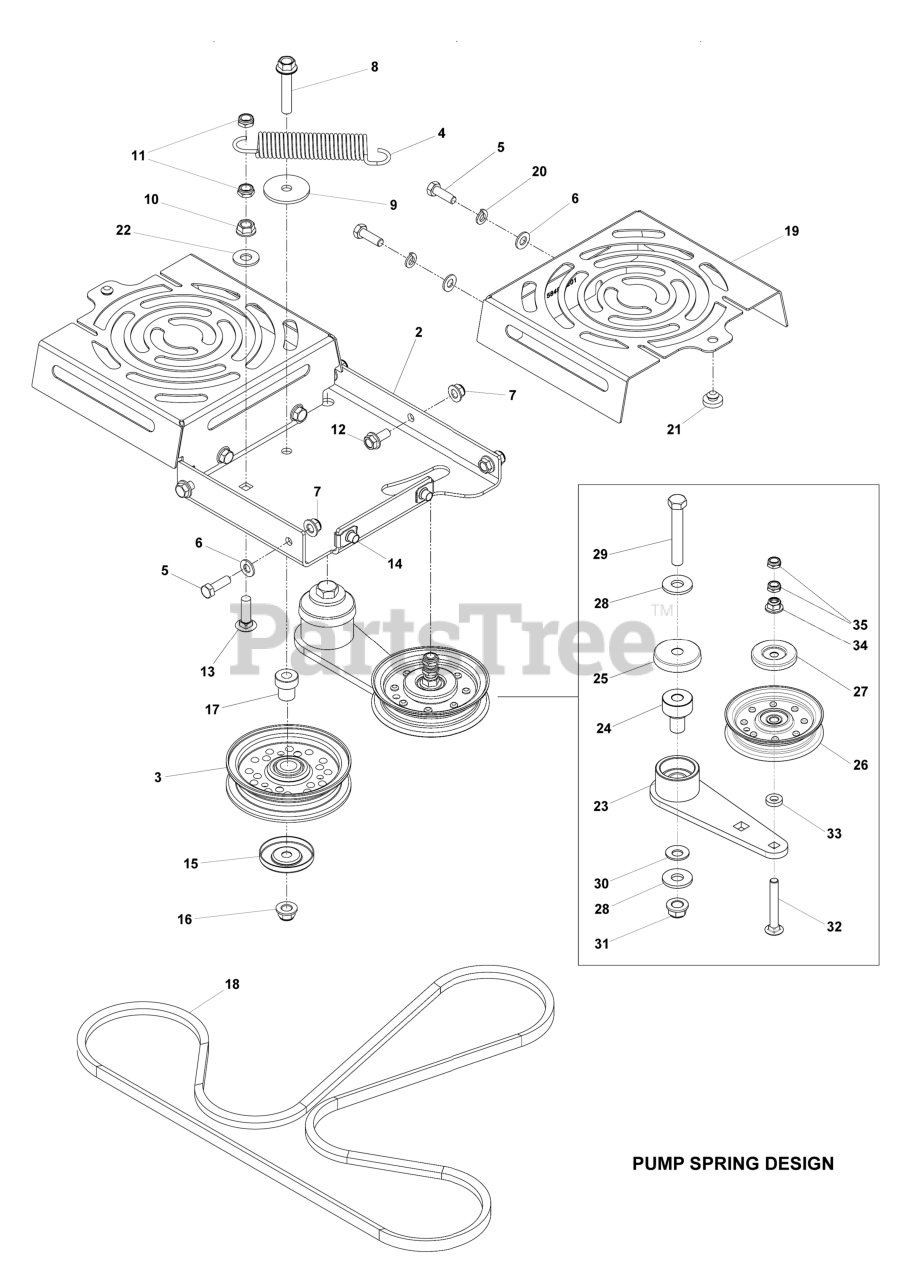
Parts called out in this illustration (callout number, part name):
2	PLATE.PNT.IDLER.SUPPORT.E-DIP
6	WASHER 11/32 X 11/16 X 14 GA T
7	NUT HEXAGON FLANGE 5/16-18 ST
14	U-CLIP 5/16-18 NUT RETAINER
15	SHIELD DUST
17	PIVOT, IDLER
18	BELT, HYDRO, 3400
19	SHIELD FAN BLACK
20	WASHER SPRING LOCK WASHER WITH
21	GROMMET, BUMPER
22	GSPW Washers
23	ARM, IDLER, STEEL, W/BGS
24	PIVOT, BEARING
25	SHIELD, DUST
26	FLAT IDLER PULLEY
27	DUST SHIELD
28	WASHER.9/16 X 1 3/8 X 12 GA.
29	HCS 1/2-13 X 3-1/4 GD 5 ZD
30	CONTACT BELLSPR 1/2
31	NUT, 1/2-13 HEX FLG NYLOC ZD
32	RHSNB 3/8-16 X 2.75
33	WASHER 3/8 X 3/4 X .187 TK
34	NUT 3/8-16 HEX FLG NYLOC ZD
35	NUT HEX 3/8-16 NYLON, THIN
